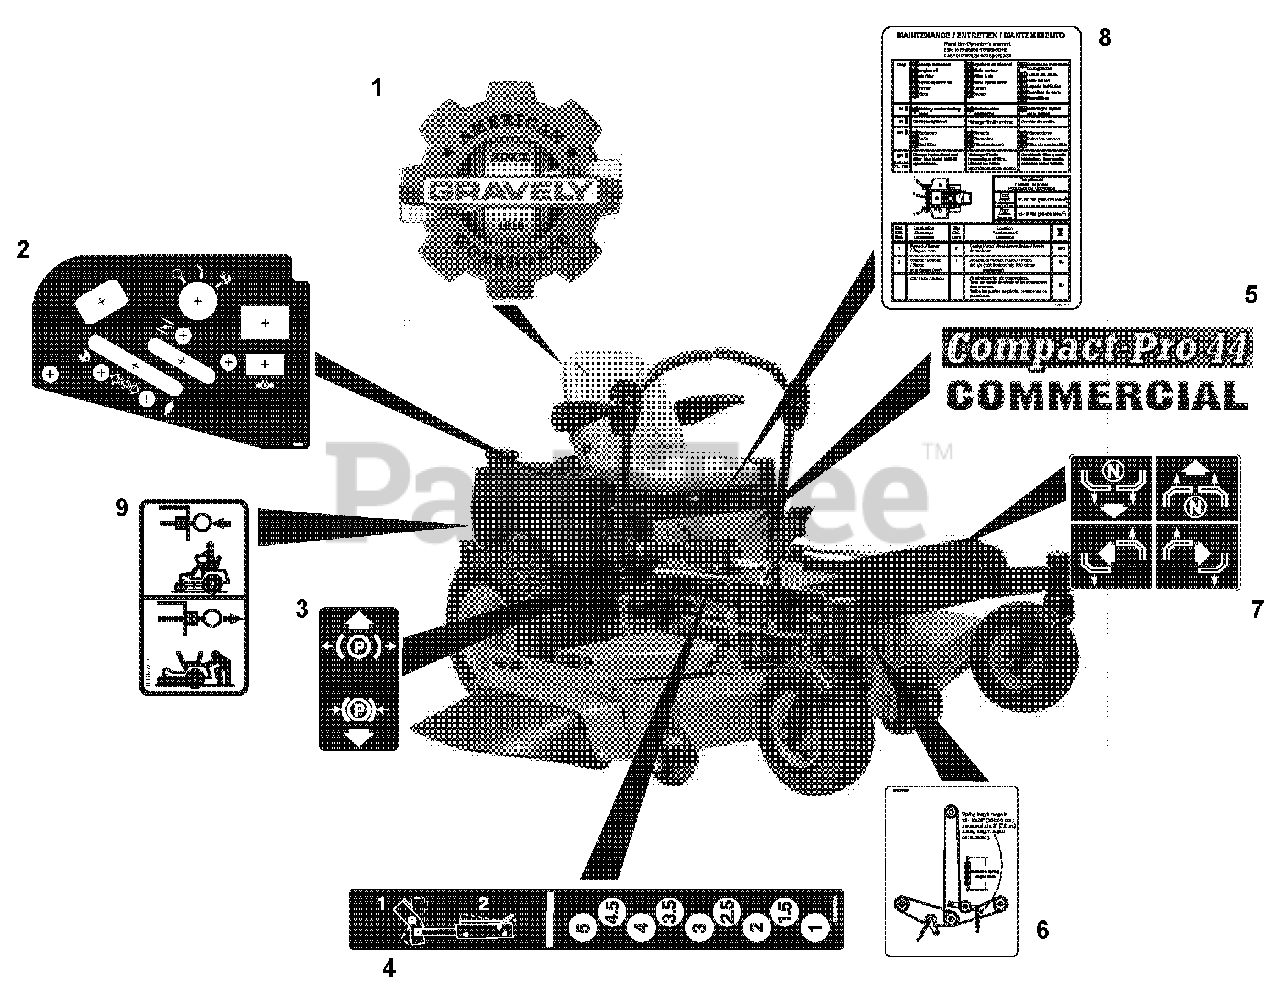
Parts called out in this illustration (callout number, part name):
1	Decal, Gravely Heritage Small
2	Decal, Control Panel
3	Decal, Parking Brake Lever
4	Decal, Height of Cut
5	Decal, Compact-Pro 44
6	Decal, Belt Diagram
7	Decal, Instructional Steering
8	Decal, Maintenance Instructions
9	Decal, Transmission Disconnect
